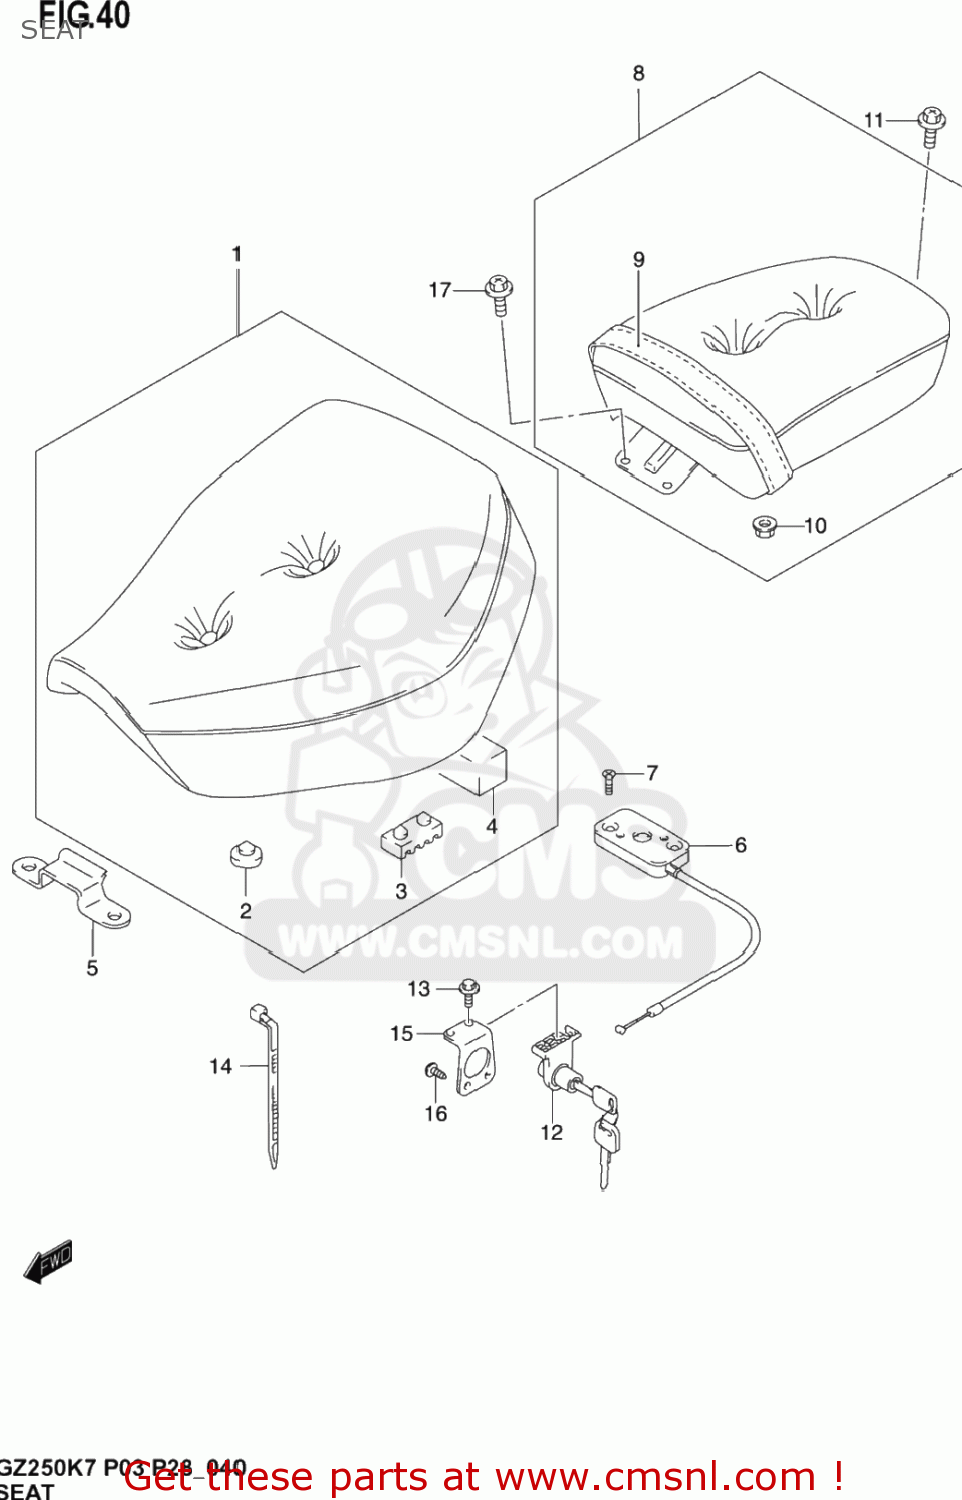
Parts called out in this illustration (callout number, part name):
1	SEAT ASSY
2	CUSHION,FRONT
3	CUSHION,RR
4	CUSHION, TOOL
5	PLATE,FR SEAT HOOK
6	BRACKET,SEAT SUPPORT
7	SCREW
8	SEAT ASSY PILLI
9	BAND, SEAT
10	NUT
11	BOLT(8X16)
12	LOCK SET,SEAT
13	BOLT
14	CLAMP(L:220)
15	BRACKET,SEAT LOCK
16	SCREW
17	BOLT(6X12)
